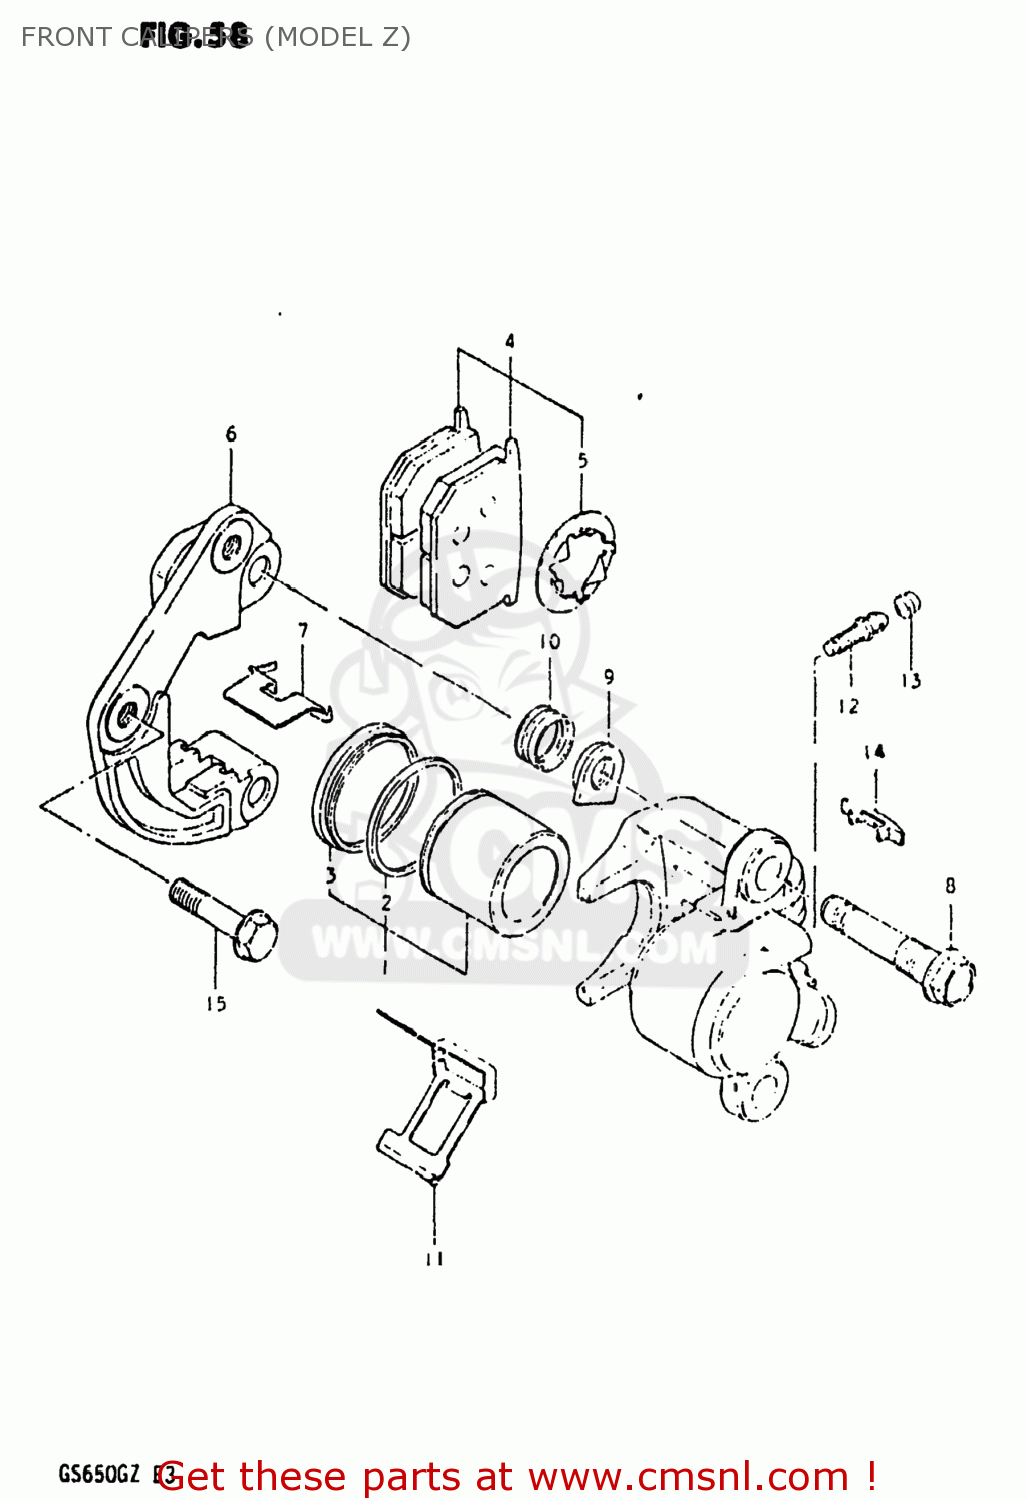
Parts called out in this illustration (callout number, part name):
0	CALIPER ASSEMBLY,LEFT
1	PISTON SET
2	SEAL,PISTON
3	BOOT,PISTON
4	PAD & SHIM SET (MCA)
5	SHIM,PAD
6	HOLDER,CALIPER,LEFT
7	PAD,GUIDE
8	AXLE,CALIPER
9	NUT,CALIPER AXLE
10	BOOT
11	SPRING
12	BREATHER
13	CAP,BLEEDER PL
14	COVER,INDICATOR
15	BOLT(10X37)
